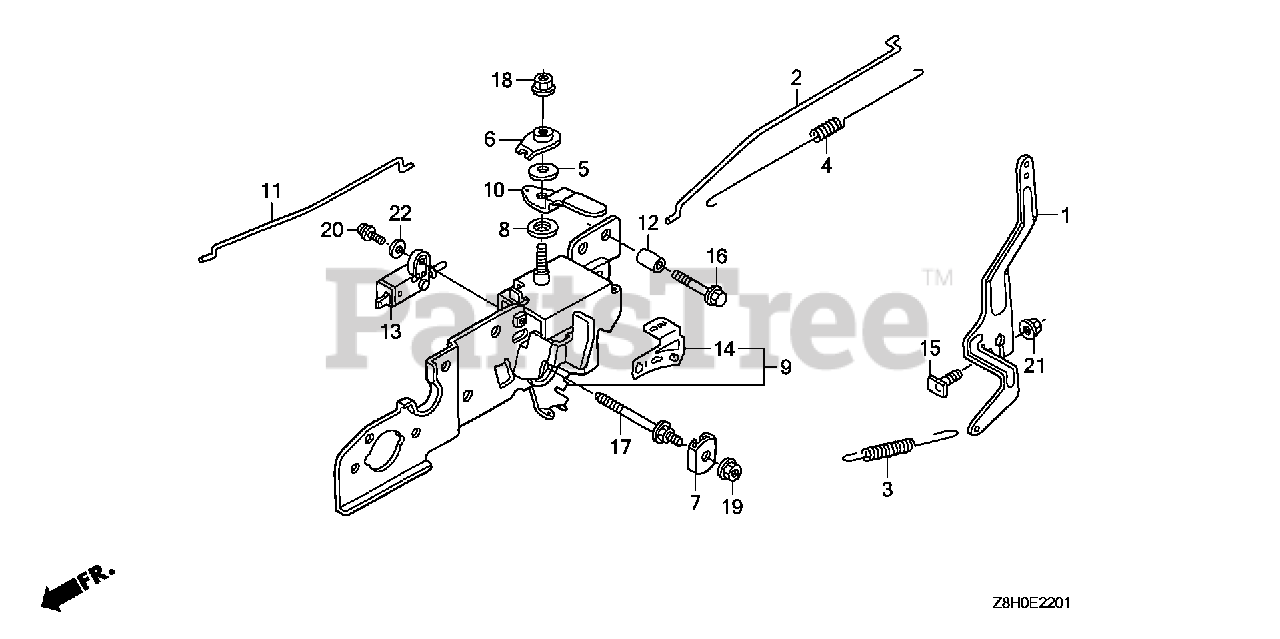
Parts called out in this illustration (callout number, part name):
1	ARM, GOVERNOR
2	ROD, GOVERNOR
3	SPRING, GOVERNOR
4	SPRING, THROTTLE RETURN
5	SPRING, LEVER
6	WASHER, CONTROL LEVER
7	PLATE, LEVER CENTER
8	SPACER, CONTROL LEVER
9	BASE, CONTROL
10	LEVER, CHOKE
11	ROD, CHOKE
12	COLLAR, IN. JOINT
13	SWITCH ASSY., ENGINE STOP (N.O)
14	MARK, THROTTLE INDICATION
15	BOLT, GOVERNOR ARM
16	BOLT, FLANGE (6X45) (CT200)
17	BOLT, SPECIAL (6X45)
18	NUT, SELF-LOCK (6MM)
19	NUT, SELF-LOCK (5MM)
20	SCREW-WASHER (4X12)
21	NUT, FLANGE (6MM)
22	WASHER, PLAIN (4MM)
